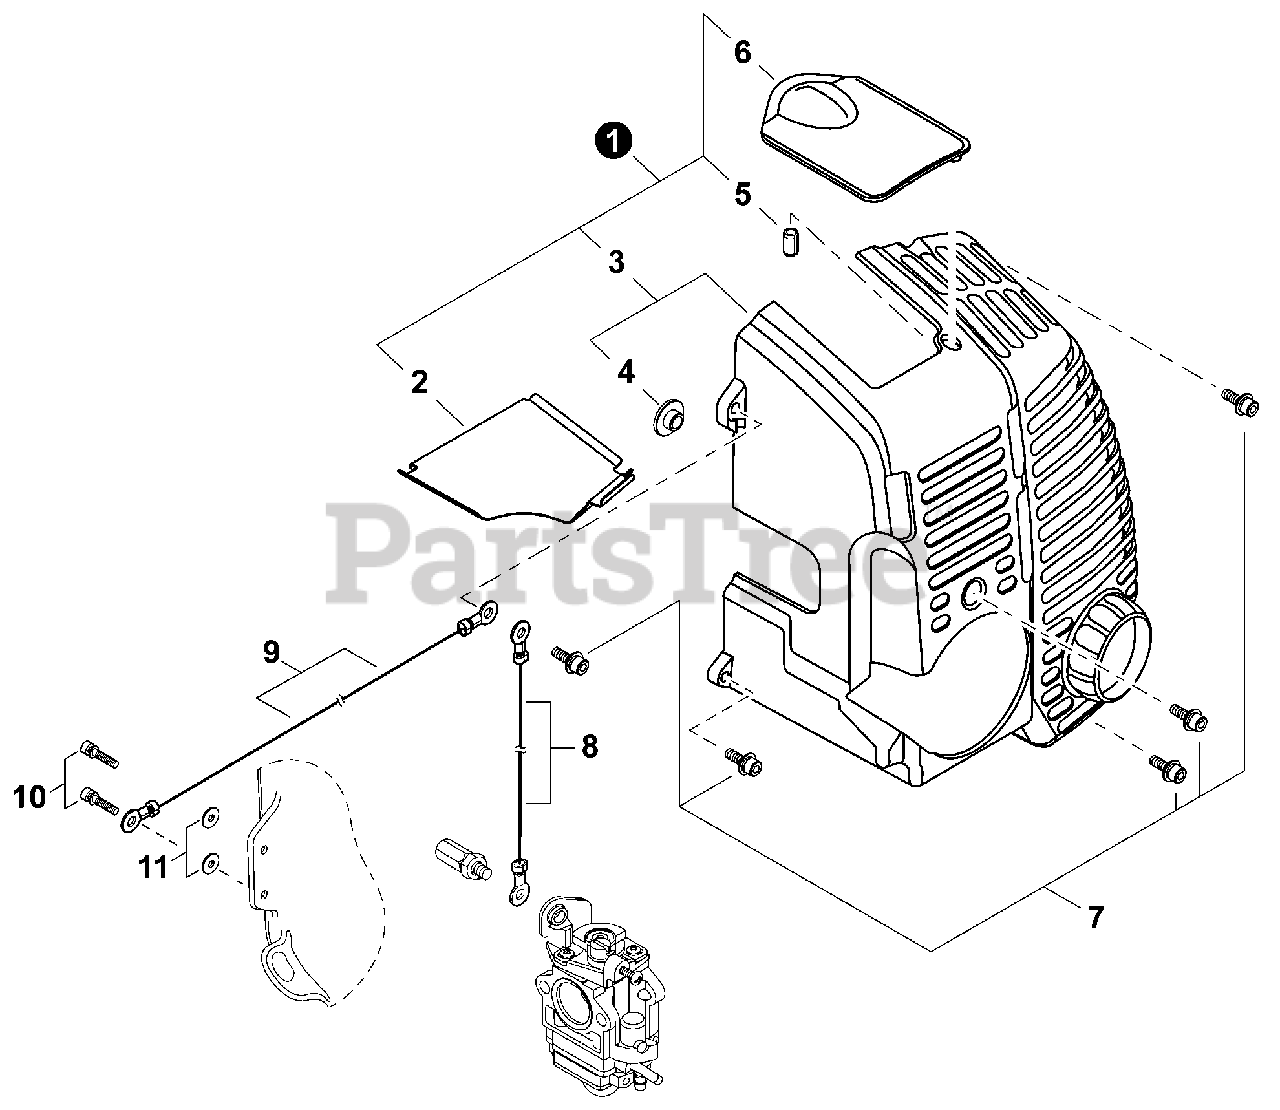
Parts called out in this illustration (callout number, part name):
1	COVER ASSY, ENGINE
2	HEAT SHIELD, EXHAUST
3	COVER, ENGINE
4	COLLAR 5
5	PIN, SPRING 4×8
6	COVER, SPARK PLUG
7	BOLT M5×18
8	WIRE, STATIC DISCHARGE 110MM
9	LEAD 0.75mm2 L= 590
10	BOLT, ADHESIVE M5×18
11	WASHER Ø15ר5.2×1.6
